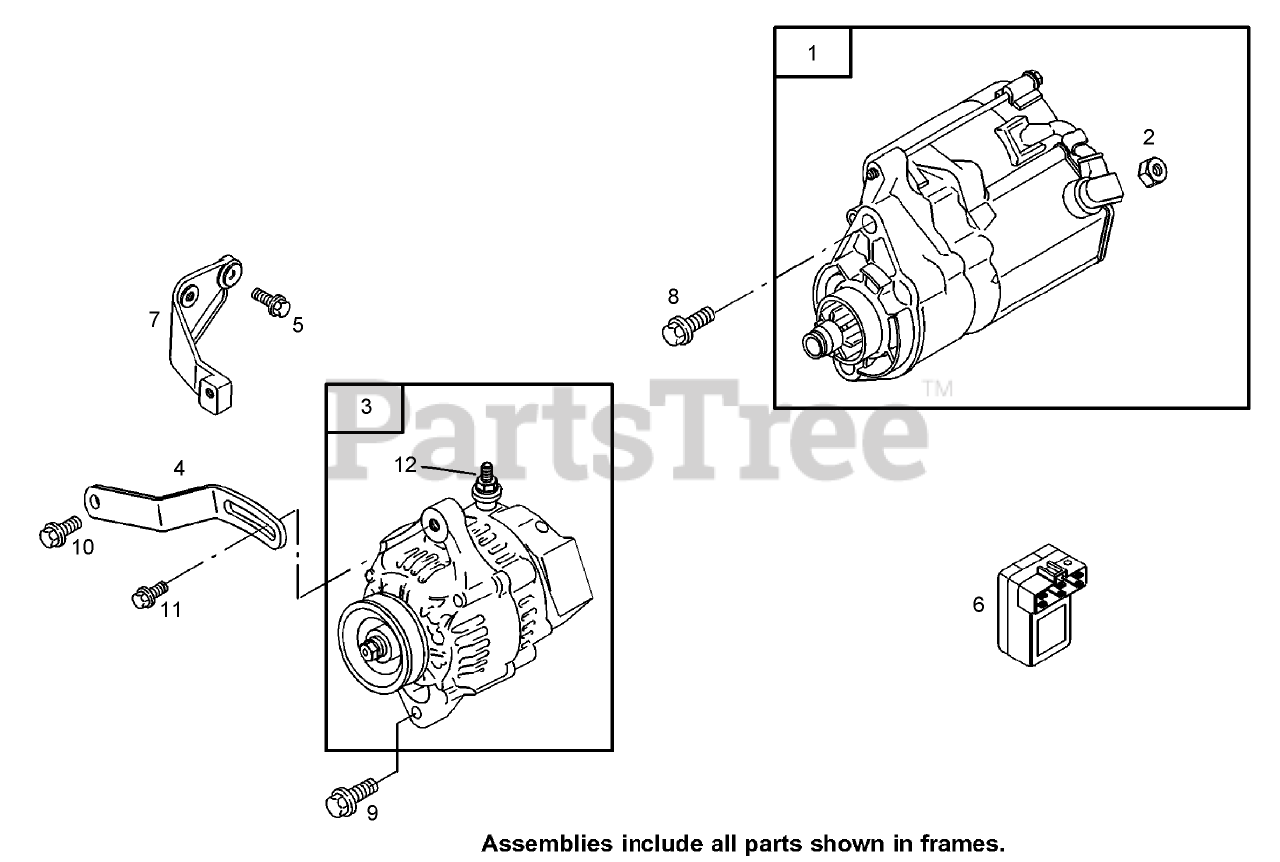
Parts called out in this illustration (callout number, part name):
1	MOTOR-STARTER
2	NUT-HEX, METRIC
3	ALTERNATOR
4	Strap-Adjusting
5	SCREW-HEX
6	MODULE
7	BRACKET-SUPPORT
8	SCREW-HEX
9	SCREW-HEX, METRIC
10	SCREW-HEX
11	SCREW-HEX, METRIC
12	NUT-HEX, METRIC
